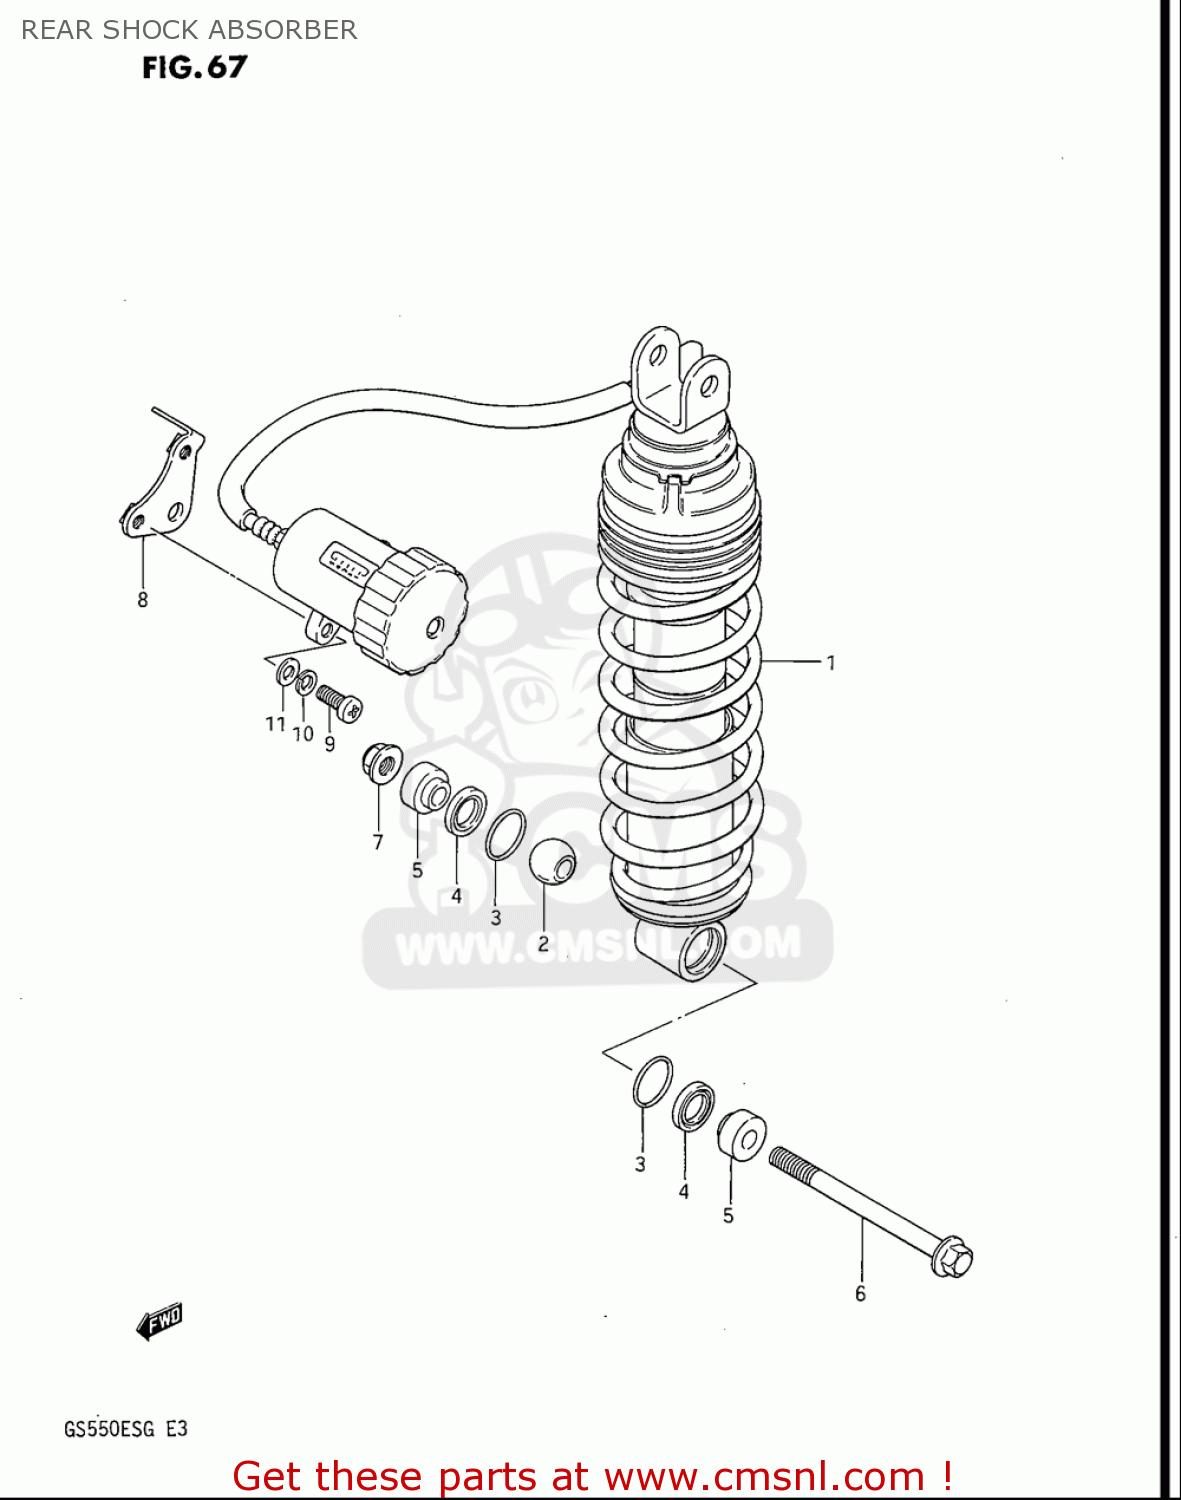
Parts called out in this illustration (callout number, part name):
2	BEARING,RR CUSHION LEVER
3	RING,STOPPER
4	SEAL,DUST
6	BOLT(10X115)
7	NUT
9	SCREW
10	WASHER,LOCK
11	WASHER
